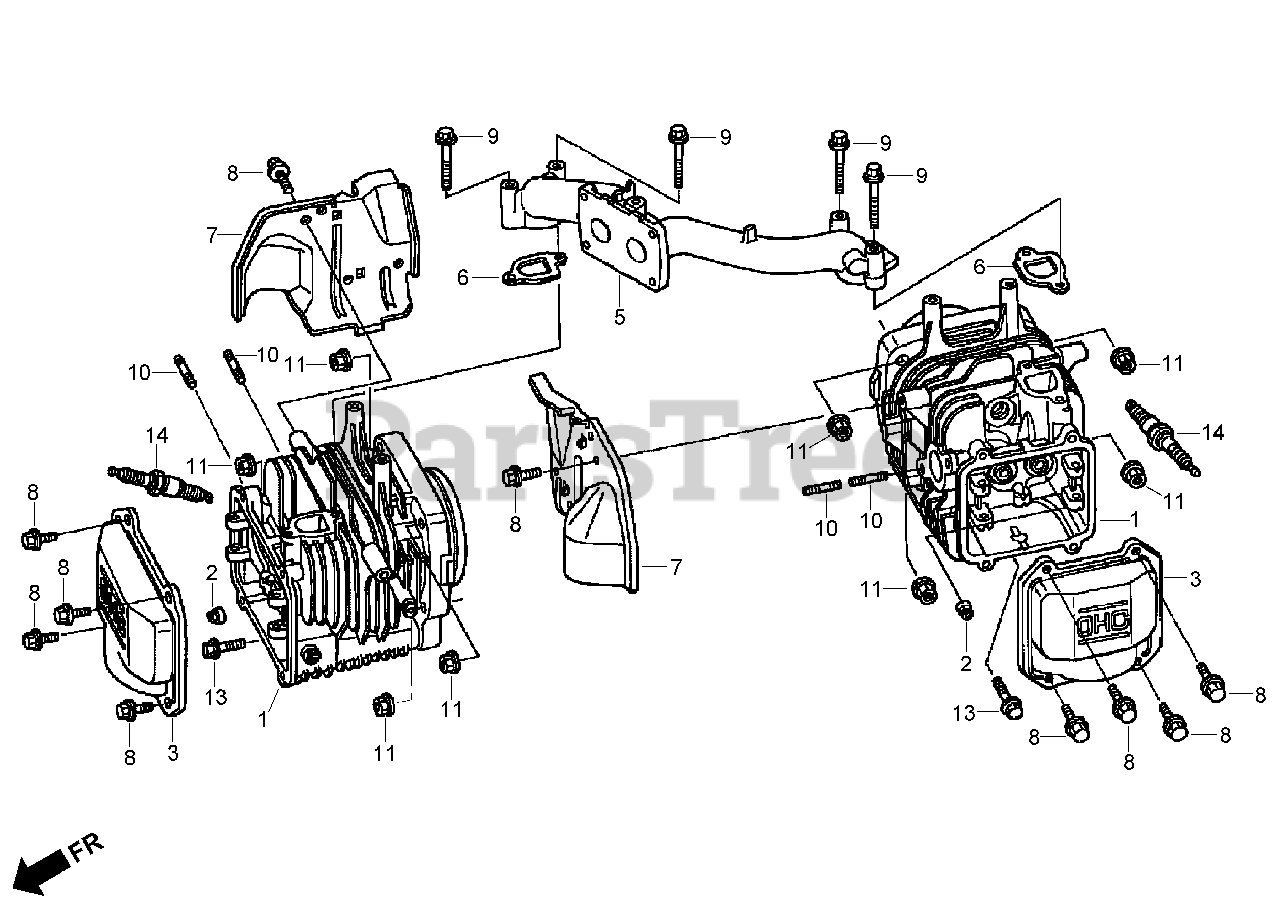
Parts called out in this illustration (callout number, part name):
1	CYLINDER
2	SEAL-STEM, VALVE
3	COVER-HEAD
5	MANIFOLD-INTAKE
6	GASKET-MANIFOLD, INTAKE
7	SHROUD
8	BOLT-FLANGE (6X12) (C T200)
9	BOLT-FLANGE (6X45) (C T200)
10	BOLT-STUD (6X28)
11	NUT-FLANGE (8MM)
13	BOLT-FLANGE (6X30)
14	SPARK PLUG (B P R4E S) (N G K)
14	SPARK PLUG (W14E P R-U) (DENSO)
14	SPARK PLUG (B P R 5E S) (N G K)
14	SPARK PLUG (W16E P R-U) (DENSO)
